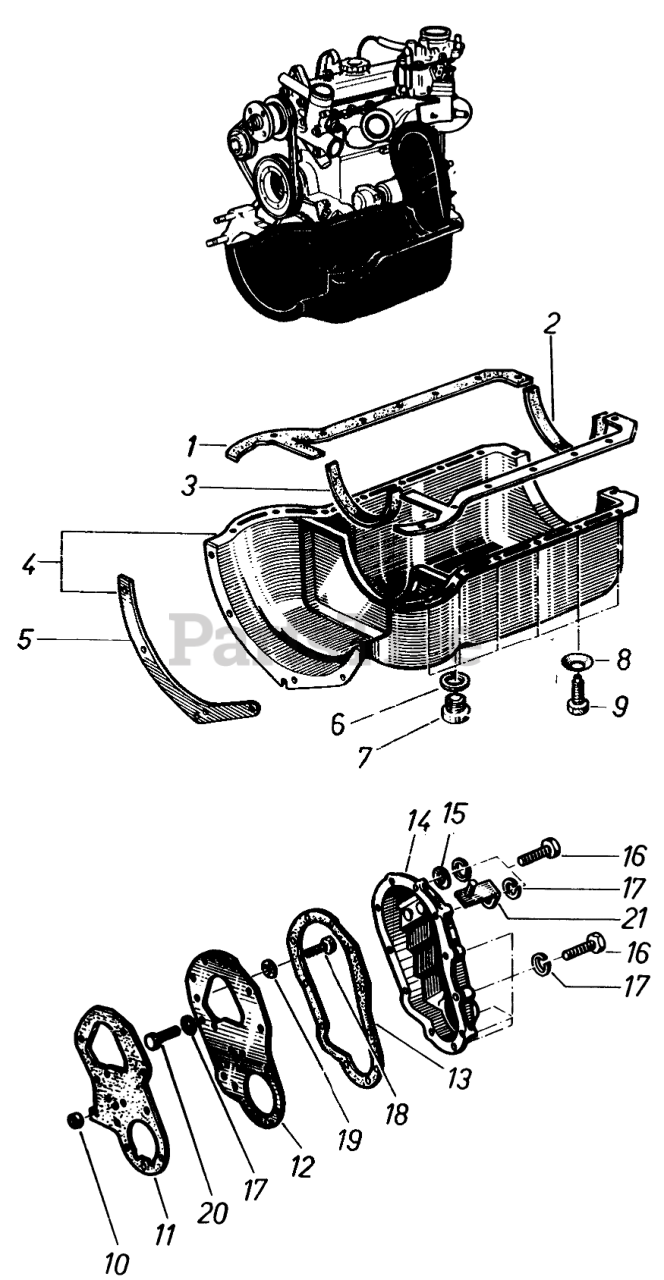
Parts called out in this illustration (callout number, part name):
1	Gasket
2	Gasket
3	Gasket
20	Screw
